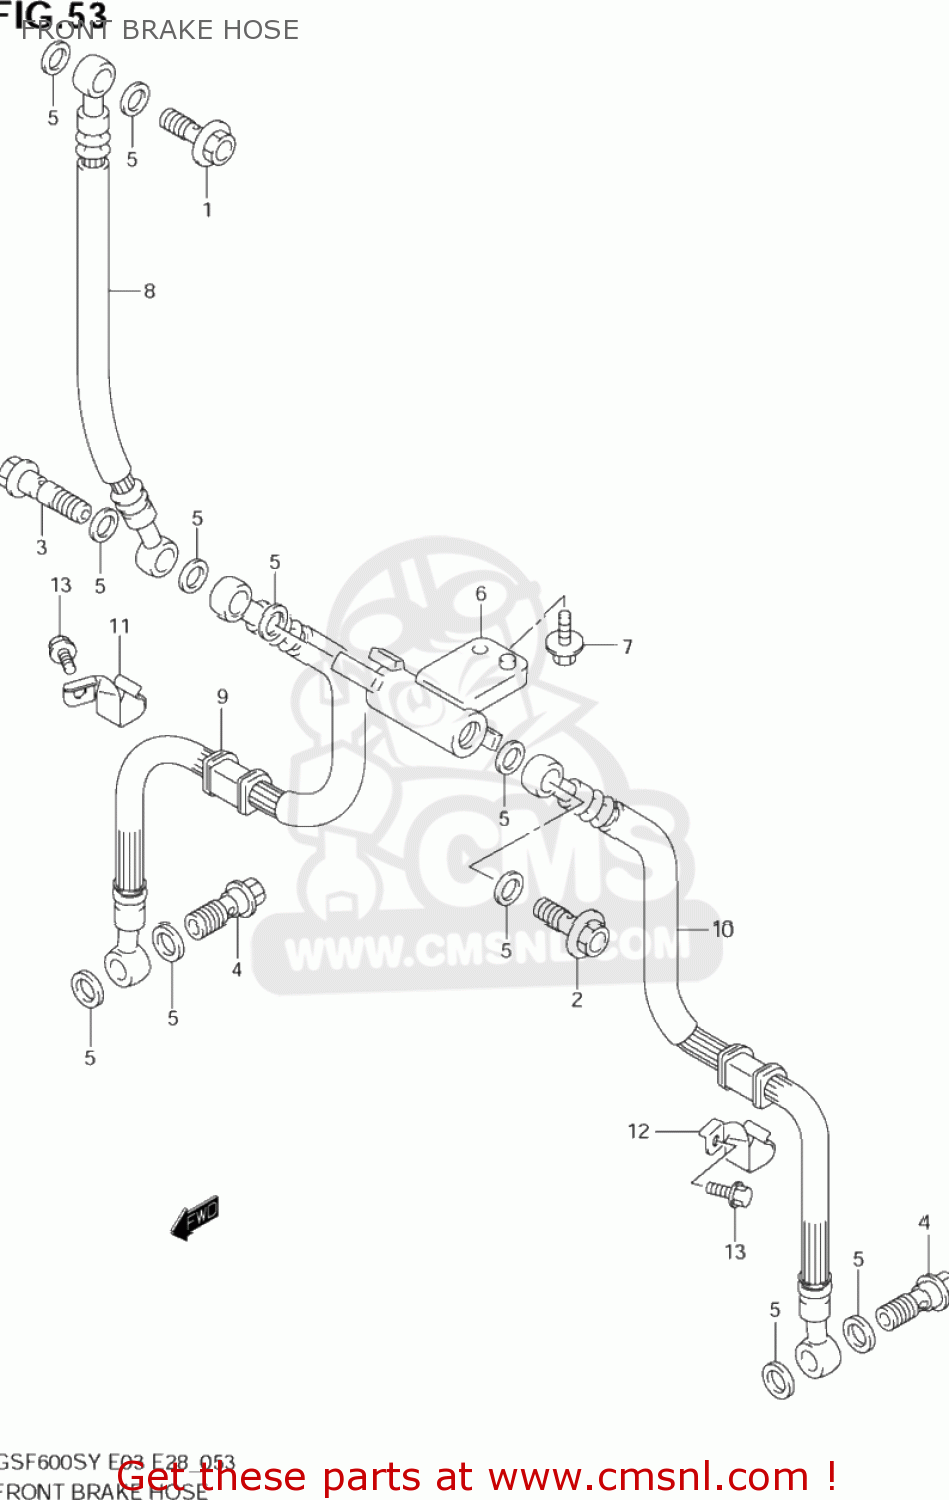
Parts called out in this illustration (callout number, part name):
1	BOLT UNION
2	BOLT UNION
3	BOLT UNION
4	BOLT UNION
5	WASHER(10X15X1.5)
6	JOINT,BRAKE HOSE
7	BOLT
8	HOSE,FR BRAKE NO.1
9	HOSE,FR BRAKE NO.2,R
10	HOSE,FR BRAKE NO.2,L
11	CLAMP,FR BRAKE HOSE NO.2,R
12	CLAMP,FR BRAKE HOSE NO.2,L
13	BOLT
